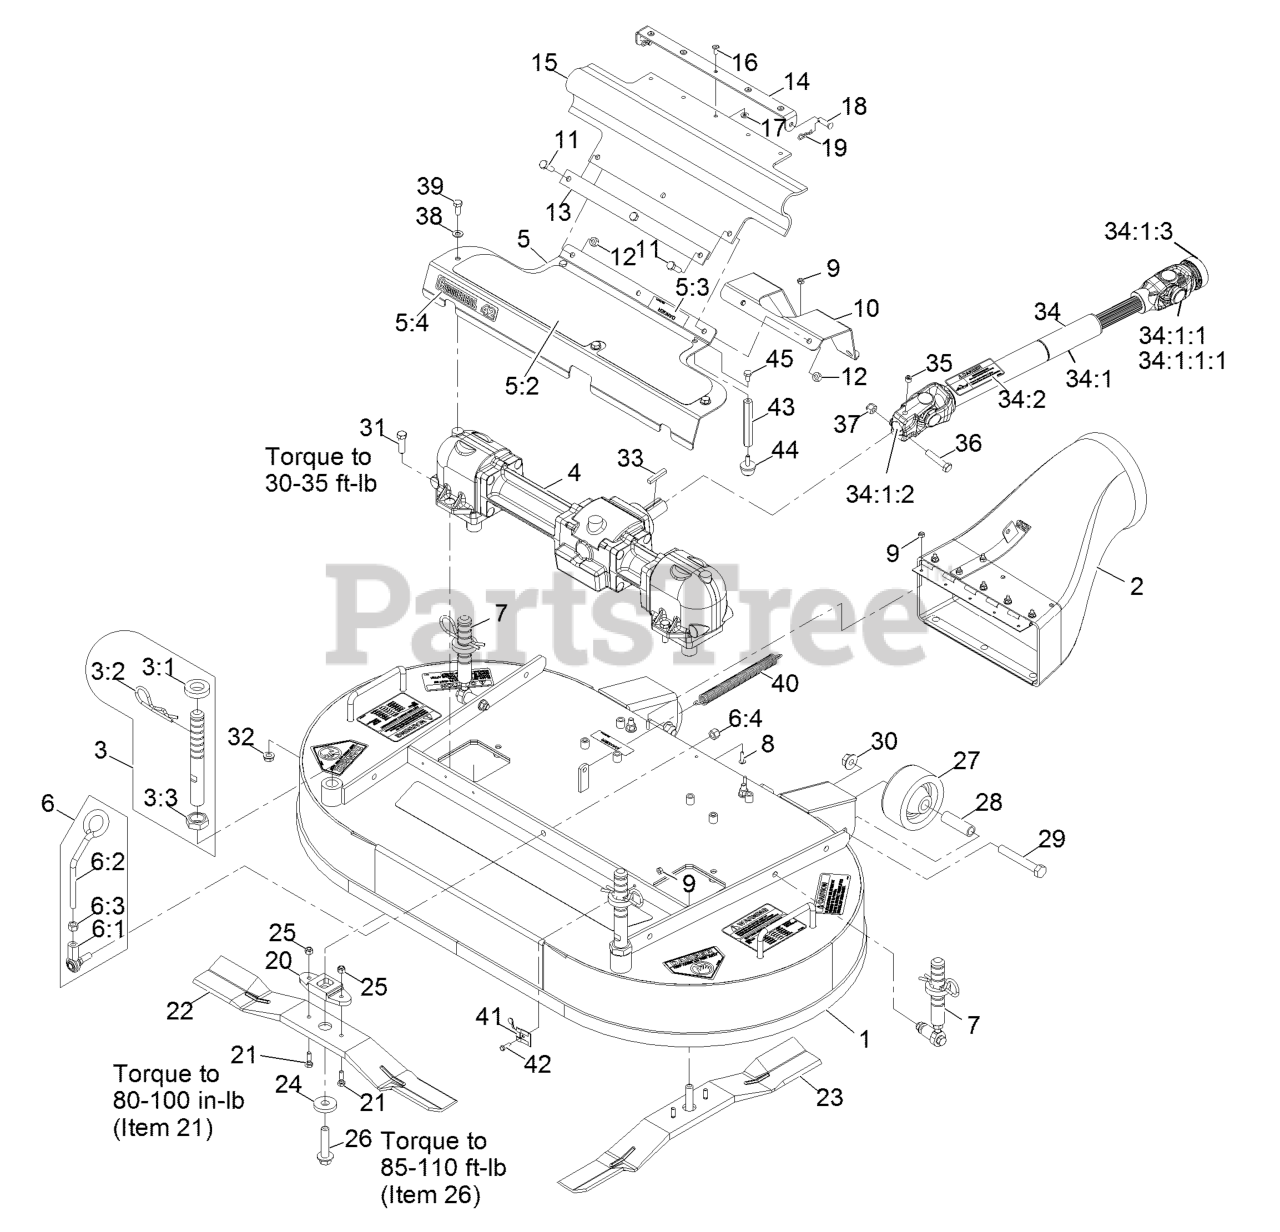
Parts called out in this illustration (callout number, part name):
1	DECK ASM
2	DISCHARGE TUBE ASM
3	FRONT DECK HEIGHT ADJUST
3:1	SPACER-DECK SUPPORT
3:2	PIN-CUT HEIGHT
3:3	NUT-JAM
4	GEARBOX ASM
5	ASM,GEARBOX COVER 42 W/DE
5:2	PAD-ANTI SKID
5:3	DECAL-COVER, MISSING
5:4	DECAL,COMMERCIAL 42
6	DECK LATCH ASM
6:1	BALLJOINT-RH
6:2	LATCH-DECK
6:3	NUT-HEX
6:4	NUT-LOCK
7	REAR DECK HEIGHT ADJUST A
8	SCREW-HEAD, TRUSS
9	NUT-LOCK, NI
10	GUARD-DRIVE SHAFT
11	SCREW-HH
12	NUT-LOCK, NI
13	STRAP-DRIVE, LINE COVER
14	BRACKET-GUARD, PTO
15	GUARD-PTO
16	RIVET-BLIND
17	WASHER-FLAT
18	PIN-CLEVIS
19	PIN-COTTER
20	DRIVER-BLADE
21	BOLT-SHEAR
22	BLADE,22 INCH RH
23	BLADE,22 INCH LH
25	NUT-LOCK, NI
26	BOLT-BLADE
27	ROLLER-DECK
28	SPACER-ROLLER
29	SCREW-HH
30	NUT-HHF
31	SCREW-HH
32	NUT-HHF, WHIZ
33	KEY-SQUARE
34	DRIVE SHAFT ASM
34:1	Shaft,Drive Telescoping
34:1:1	U-JOINT KIT
34:1:1:1	FITTING-GREASE
34:1:2	YOKE-KEYED
34:1:3	YOKE-QUICK DISCONNECT
34:2	DECAL-DRIVELINE
35	SCREW-SET, HSH
36	SCREW-HH
37	NUT-LOCK, NI
38	WASHER-PLAIN
39	SCREW-HH
40	SPRING-EXTENSION
41	CLIP-DECK, HOLD UP ROD
43	STAND-OFF
45	SCREW-HH
